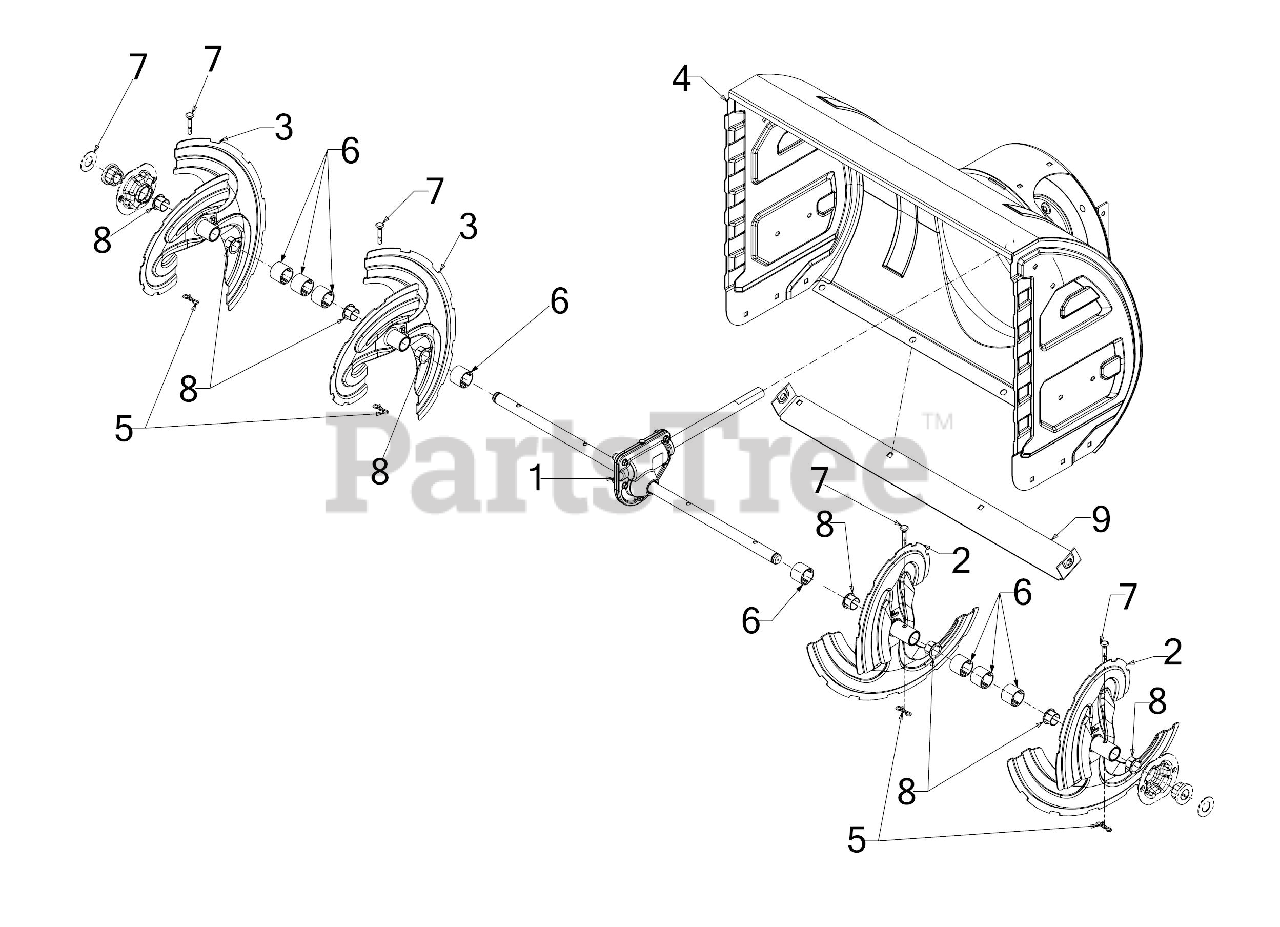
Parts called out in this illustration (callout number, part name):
1	28" GEARBOX ASSEMBLY
2	AUGER ASSEMBLY (LH)
3	AUGER ASSEMBLY (RH)
4	28" AUGER HOUSING
5	BOW TIE COTTER PIN 1/4-5/16
6	SPACER 1.25OD x .75ID X1.00 LG
7	SHEAR PIN .25 x 1.50 GR2
8	FLANGE BUSHING
9	28" SHAVE PLATE
